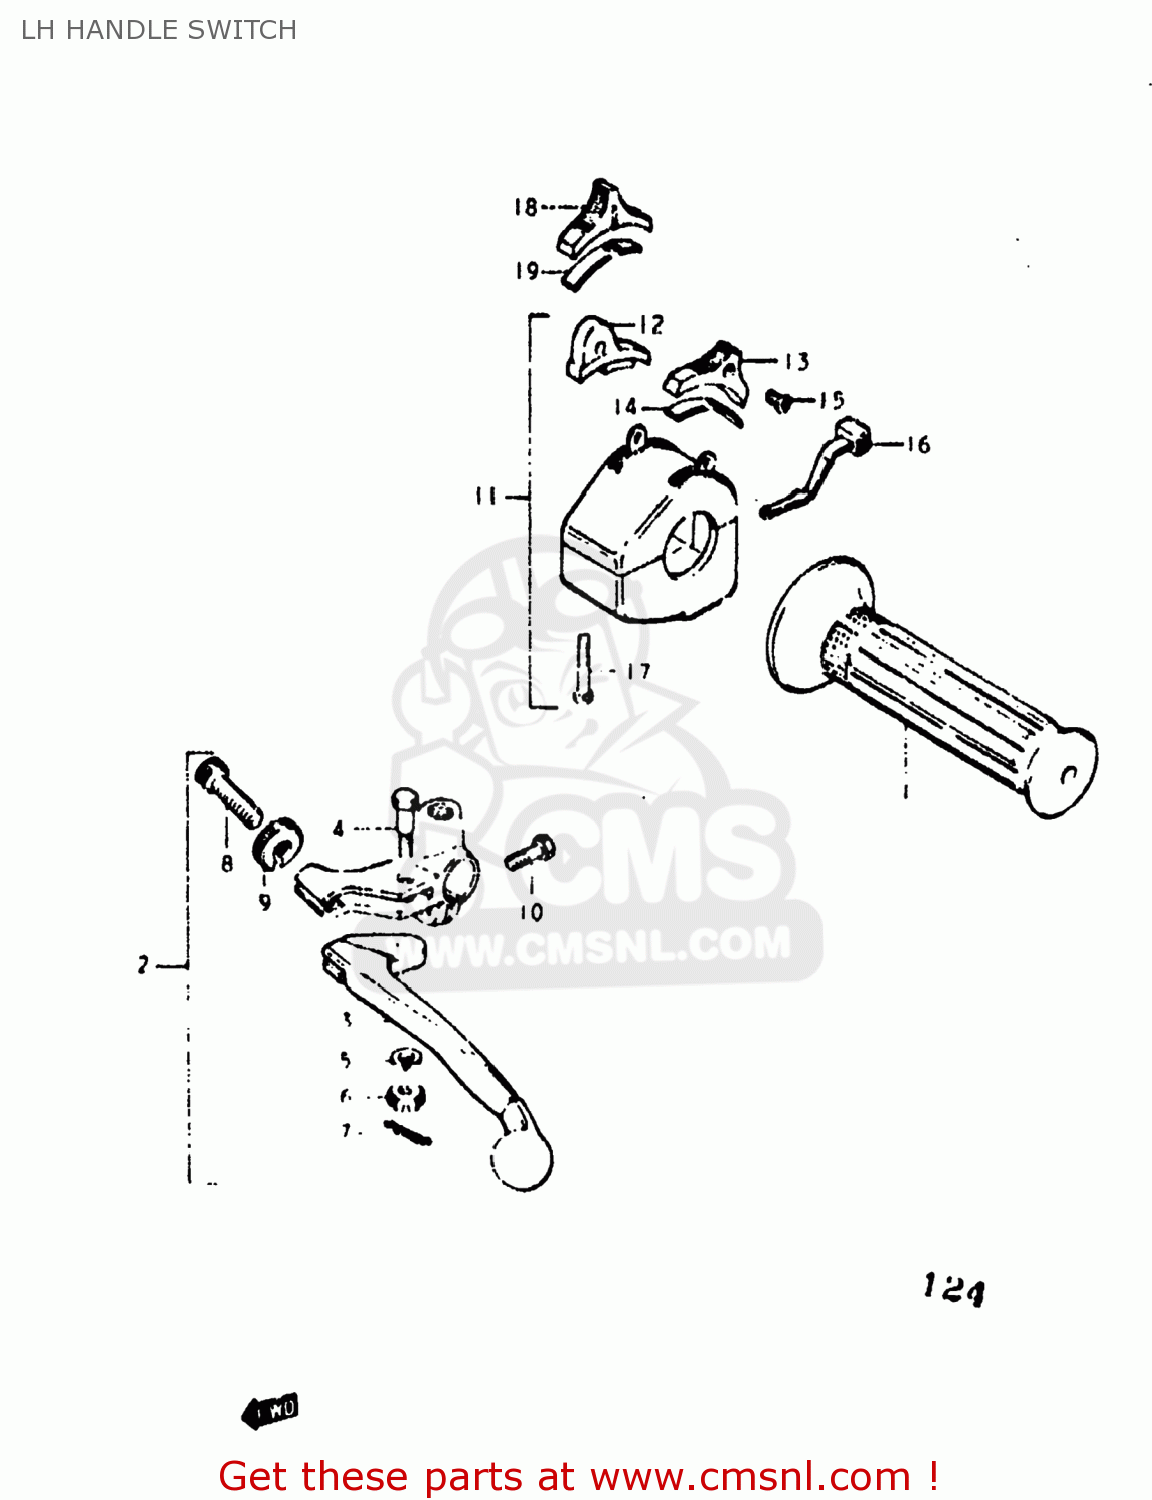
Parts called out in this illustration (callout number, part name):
1	GRIP,LEFT
2	LEVER ASSEMBLY
3	LEVER,CLUTCH
4	BOLT,LEVER
5	LOCK WASHER
6	NUT,LEVER FITTNG
7	COTTER PIN
8	ADJUSTER,CABLE
9	NUT,CABLE ADJUSTER
10	BOLT
11	SWITCH ASSEMBLY,HANDLE,LEFT
13	KNOB,HANDLE SWITCH
14	PLATE,SWITCH KNOB
15	SCREW
16	KNOB, TURN SIGNAL LAMP SWITCH B,XB
17	SCREW
18	KNOB,HANDLE SWITCH
19	PLATE,SWITCH KNOB
